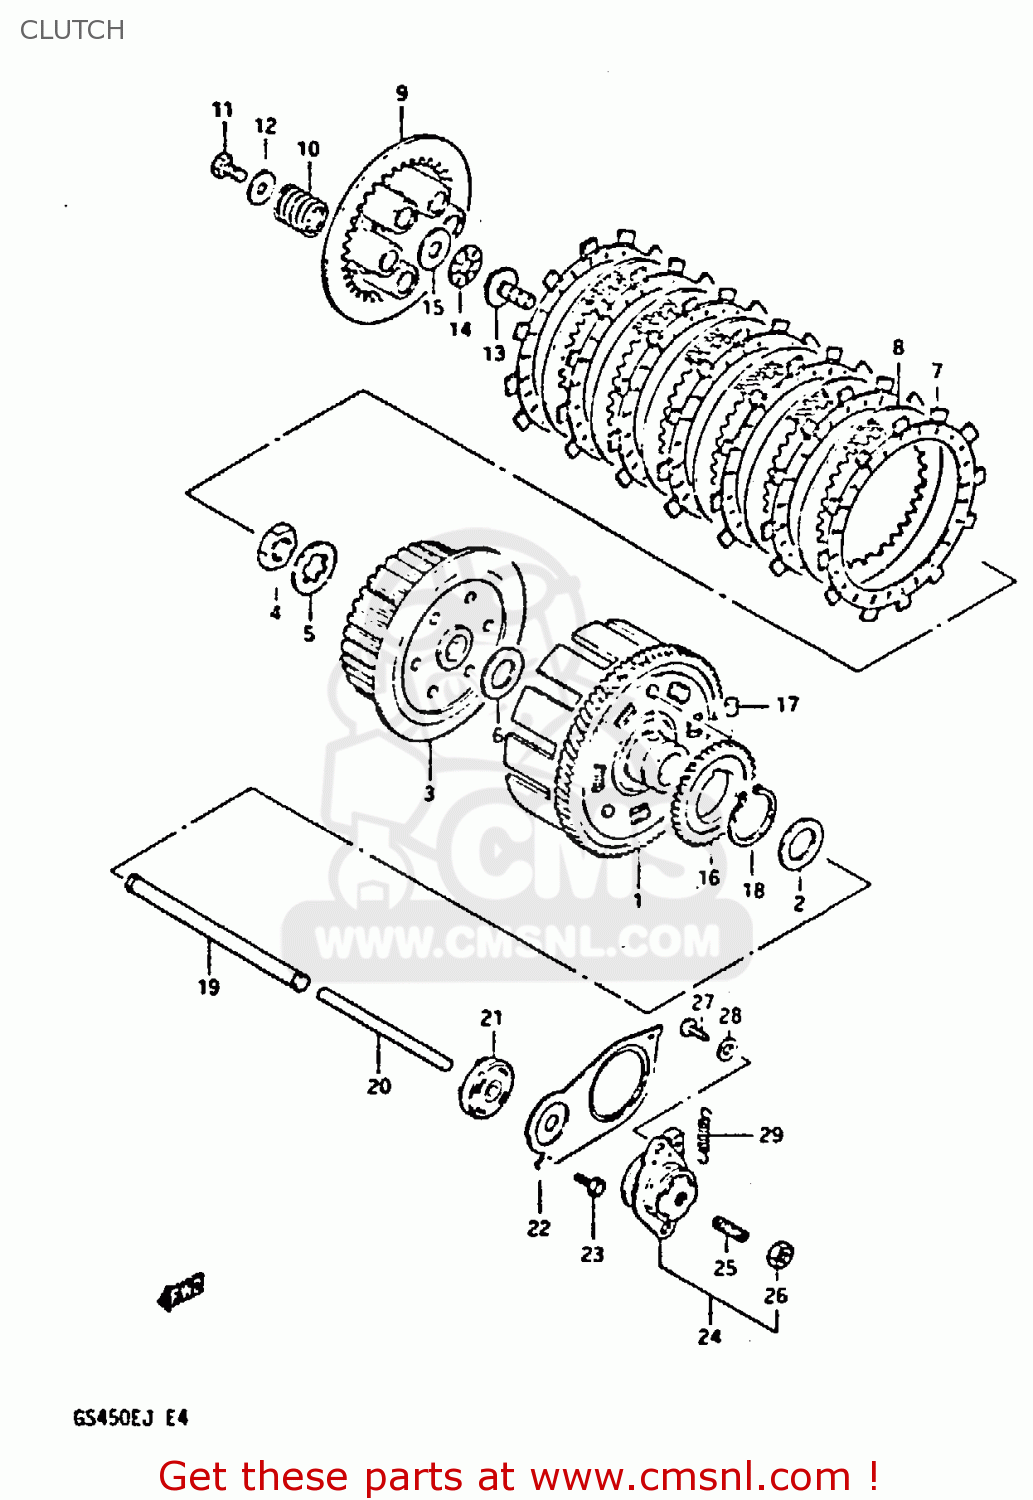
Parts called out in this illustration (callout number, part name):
1	GEAR ASSEMBLY,PRIMARY DRIVE
2	WASHER
3	HUB,CLUTCH SLEEVE
4	NUT (20MM)
5	WASHER,LOCK
6	WASHER(20X44X3)
7	PLATE,CLUTCH DRIVE (NAS)
8	PLATE,CLUTCH DRIVEN (NAS)
9	DISC,CLUTCH PRESSURE
10	SPRING
11	BOLT
12	WASHER
13	PIECE,CLUTCH PUSH
14	BEARING(15X28X2)
15	WASHER
16	GEAR,OIL PUMP DRIVE
17	PIN(6X6)
18	CIRCLIP
19	ROD,PUSH,R
20	ROD,CLUTCH PUSH
21	SEAL,OIL(6X34X10)
22	PLATE,CLUTCH PUSH ROD
23	BOLT
24	SCREW ASSY,CLUTCH RELEASE
25	SCREW(6X25)
26	NUT 6MM
27	SCREW
28	WASHER
29	SPRING
